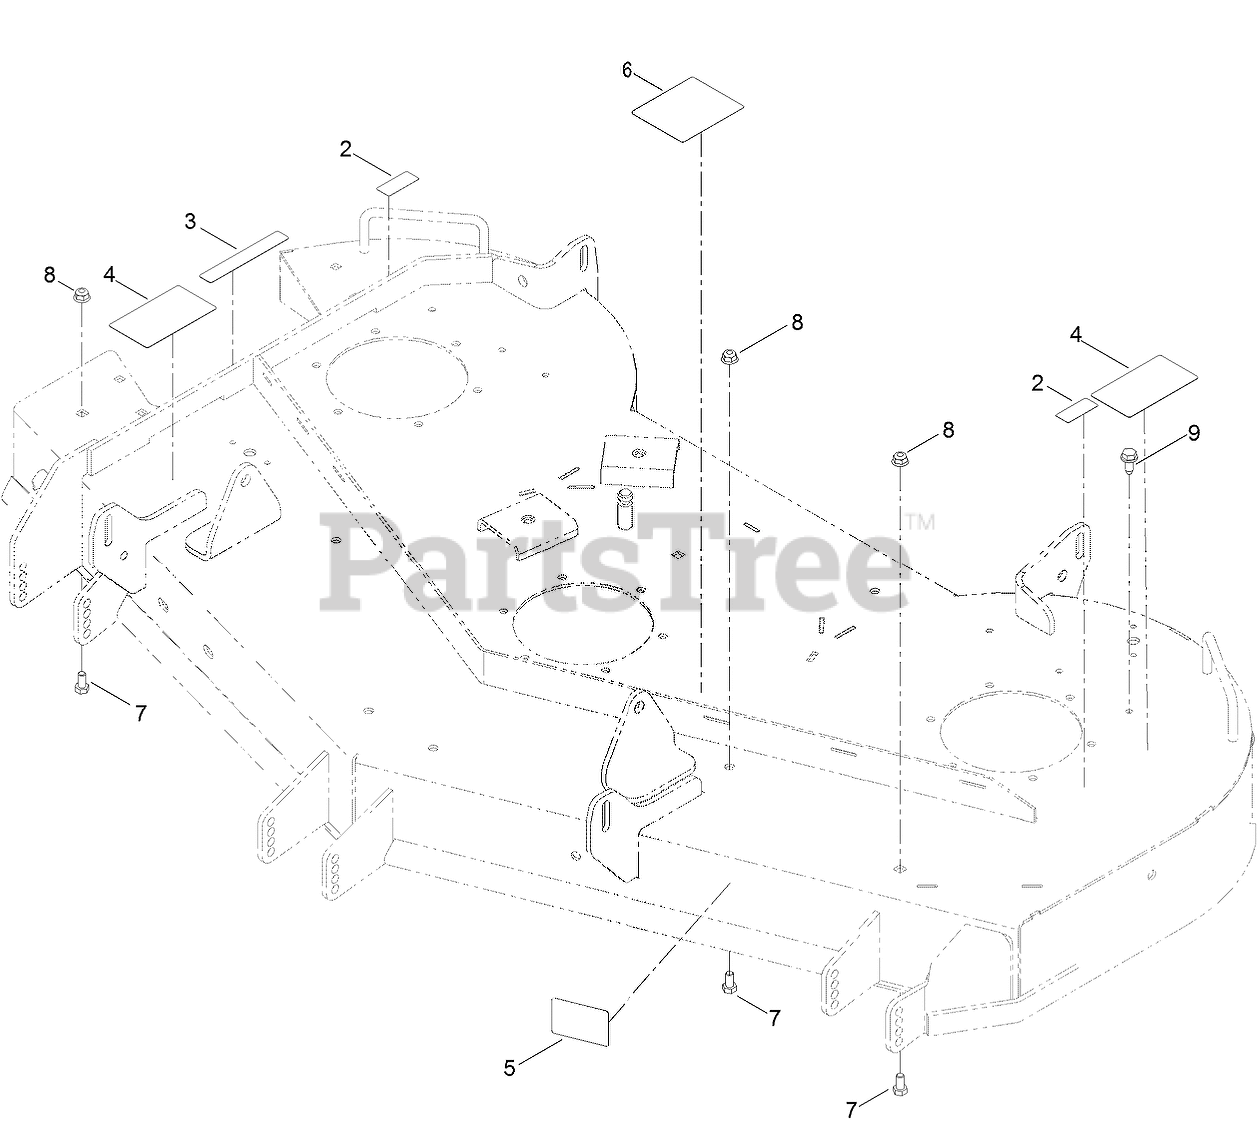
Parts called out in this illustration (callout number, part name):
2	DECAL-DANGER
3	DECAL-DANGER
4	DECAL-DANGER
5	DECAL-SCALP, ANTI
6	DECAL-ROUTING, BELT
7	SCREW-HH
8	NUT-HF, NI
9	SCREW-HWHTF
